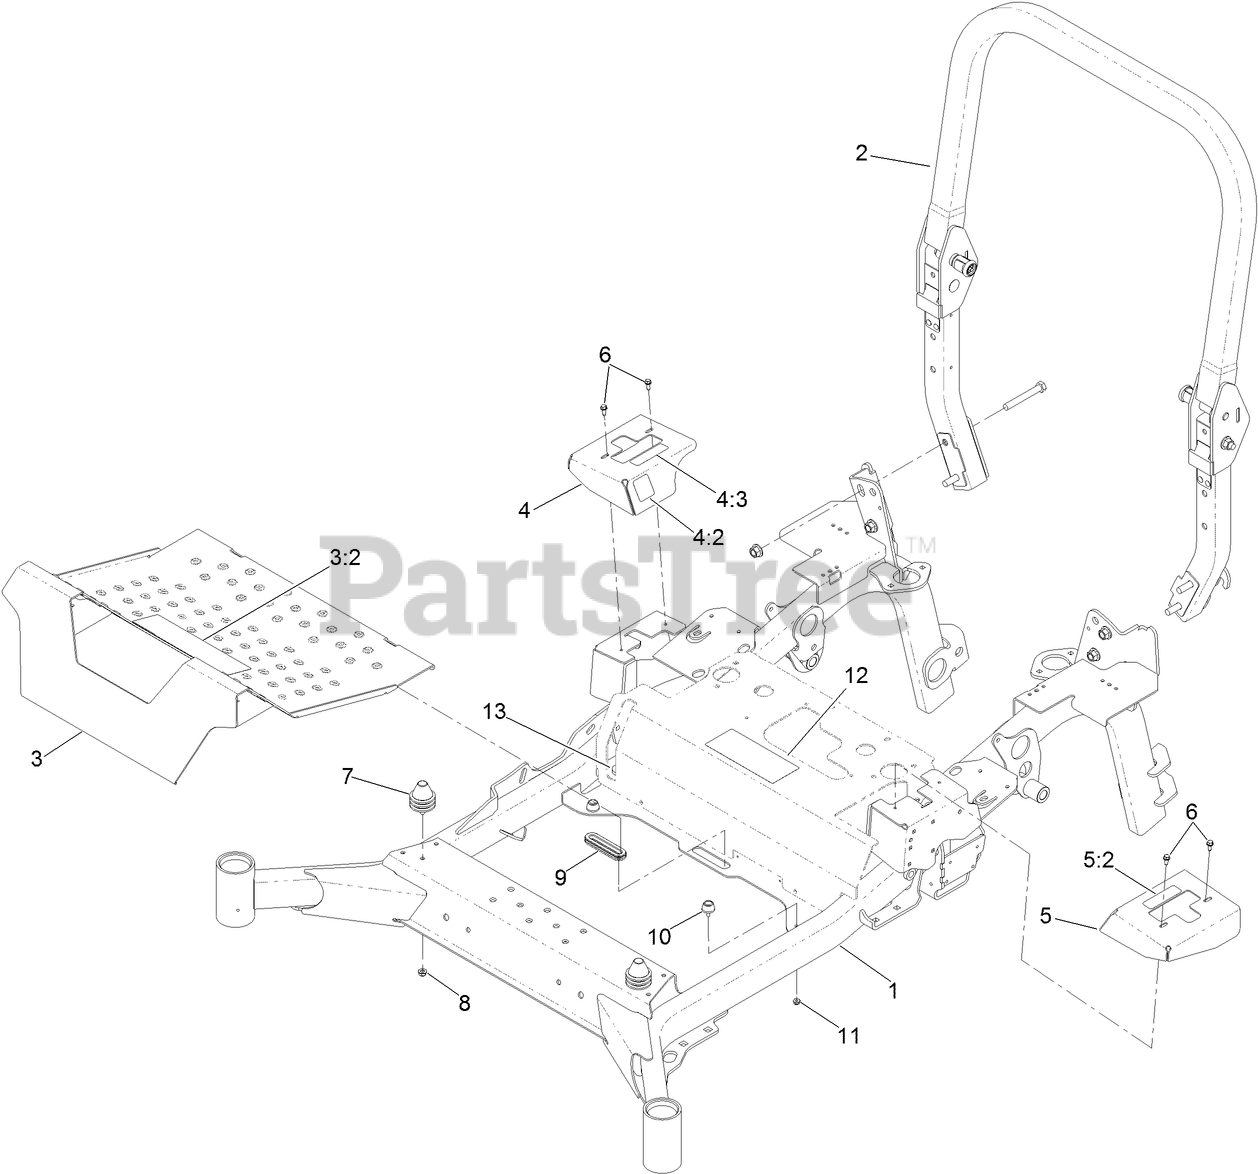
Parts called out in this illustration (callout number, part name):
1	FRAME-MAIN
2	ROPS ASM
3	COVER-MOTION CONTROL, LH
3:2	DECAL-DANGER
4	COVER-MOTION CONTROL, RH
4:2	DECAL-CONTROL, MOTION
4:3	DECAL-PARK BRAKE, CE
5	COVER-MOTION CONTROL, LH
5:2	DECAL-CONTROL, MOTION
6	SCREW-HWH
7	ISOLATOR
8	NUT-HF, NI
9	GROMMET-RUBBER
10	BUMPER-RUBBER
11	NUT-HF
12	DECAL-SERVICE AID
13	BUMPER-PUSH-IN, RUBBER
